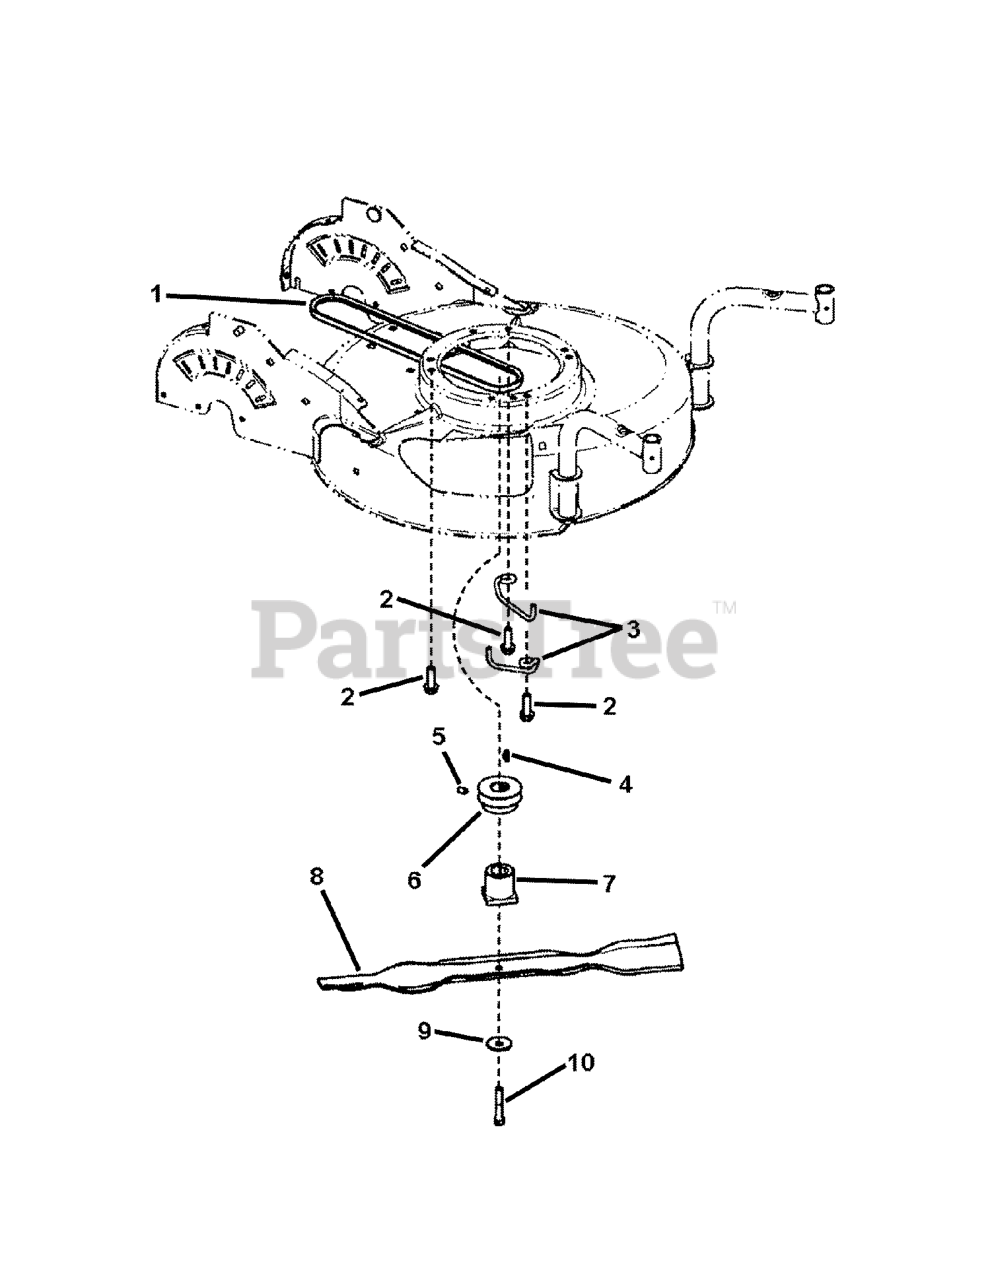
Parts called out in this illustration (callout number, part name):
1	BELT, 3L, TRACTION DRIVE, 21" PIVOT HANDLE
2	SCREW, 3/8-16 x 1-1/4" Hex Washer Self-Tap
3	GUIDE, BELT, JS45
4	KEY, #HP-506 HI-PRO
5	HRSS, 5/16-18X1/2
6	PULLEY, ENGINE, .9875 ID, 2.5" OD, 1.20" thick
7	HUB, BLADE, 21" WBM, RD, 2 POSITION
8	BLADE, WAVE, 21" STEEL DECK
9	WASHER, CONE
10	HHCS, 3/8-24X2 GR5
